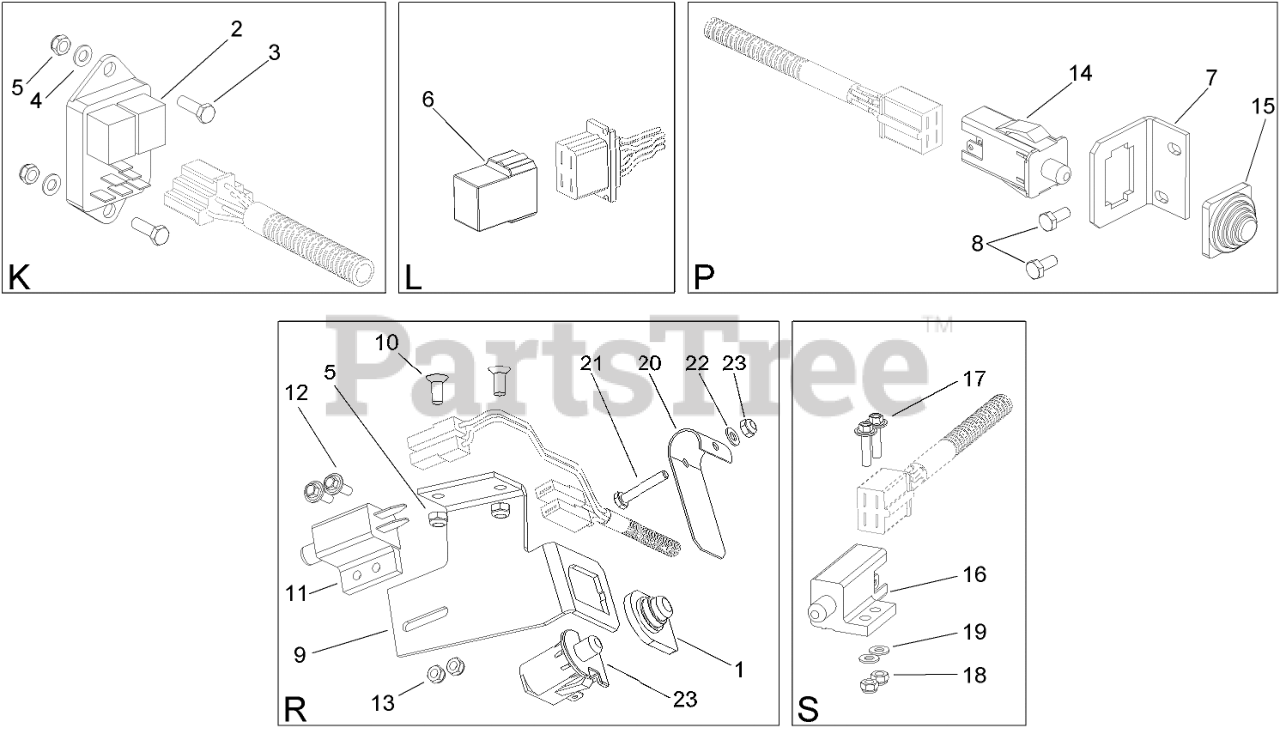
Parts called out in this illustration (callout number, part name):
1	COVER-PROTECTIVE
2	MODULE-CLUTCH
3	SCREW-HH
4	WASHER
5	NUT-LOCK
6	CIRCUIT-MEMORY
7	Holder-Switch
9	Holder-Switch
11	SWITCH-POLE, SINGLE
13	NUT-HEX
14	Switch-Delta
15	Cover-Switch
16	Switch-Delta
18	NUT-LOCK
19	WASHER
20	Lever-Spring
21	SCREW-HEX
22	Washer
23	SWITCH-DELTA
